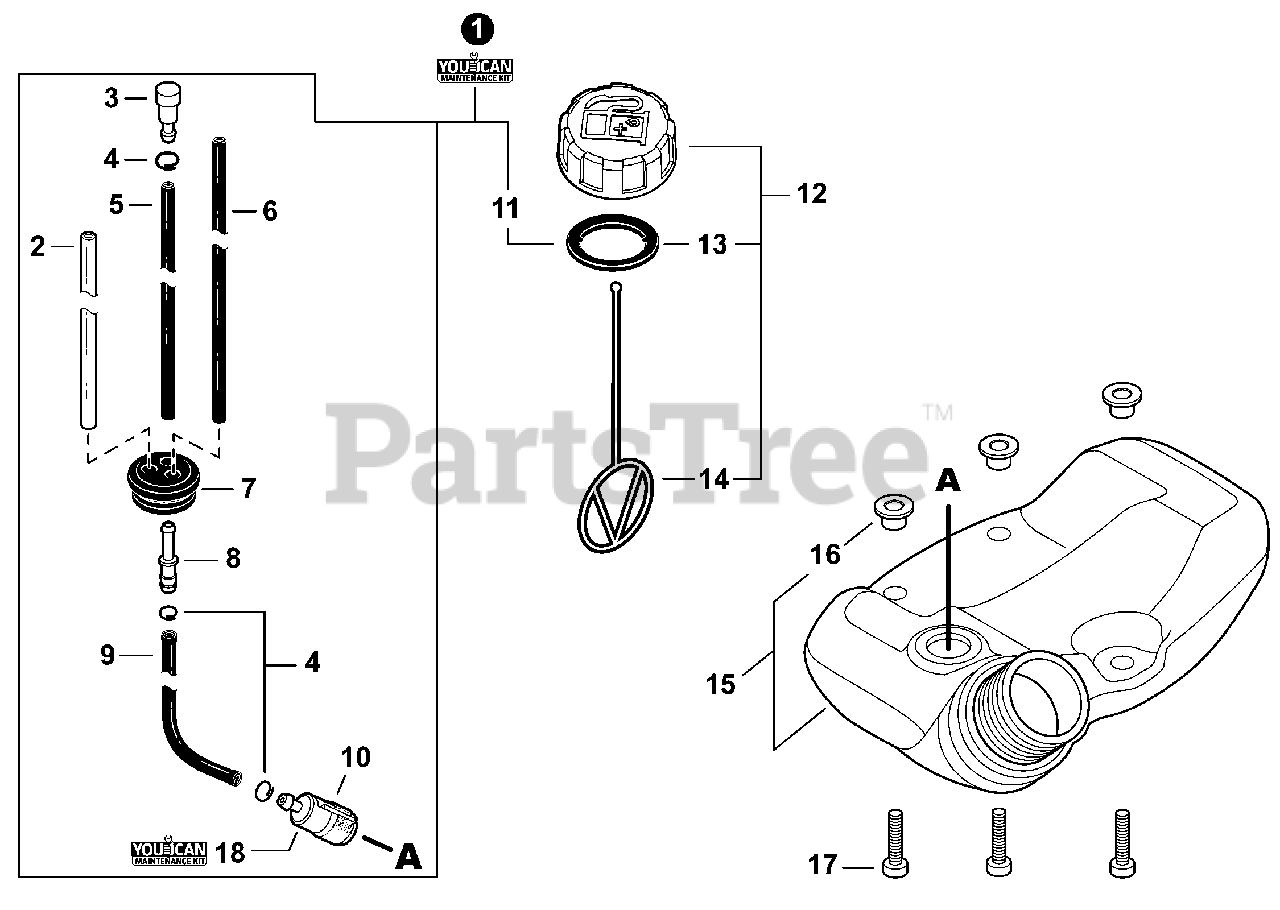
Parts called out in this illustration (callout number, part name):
1	FUEL SYSTEM KIT - YOUCAN™
2	PIPE, FUEL 3×6×80 CLEAR
3	VENT ASSY
4	CLIP Ø6
5	PIPE, FUEL 3×5×90 BLACK
6	PIPE, FUEL 3×5×74 BLACK
7	GROMMET, FUEL Ø5
8	CONNECTOR, PIPE Ø5ר3.5
9	PIPE, FUEL 3×5×130 BLACK
10	FILTER, FUEL
11	GASKET, FUEL CAP
12	CAP ASSY, FUEL
13	GASKET, FUEL CAP
14	CONNECTOR, CAP L= 123
15	TANK ASSY, FUEL
16	COLLAR 5
17	BOLT, TORX 5×20
18	TUNE-UP KIT - YOUCAN™
